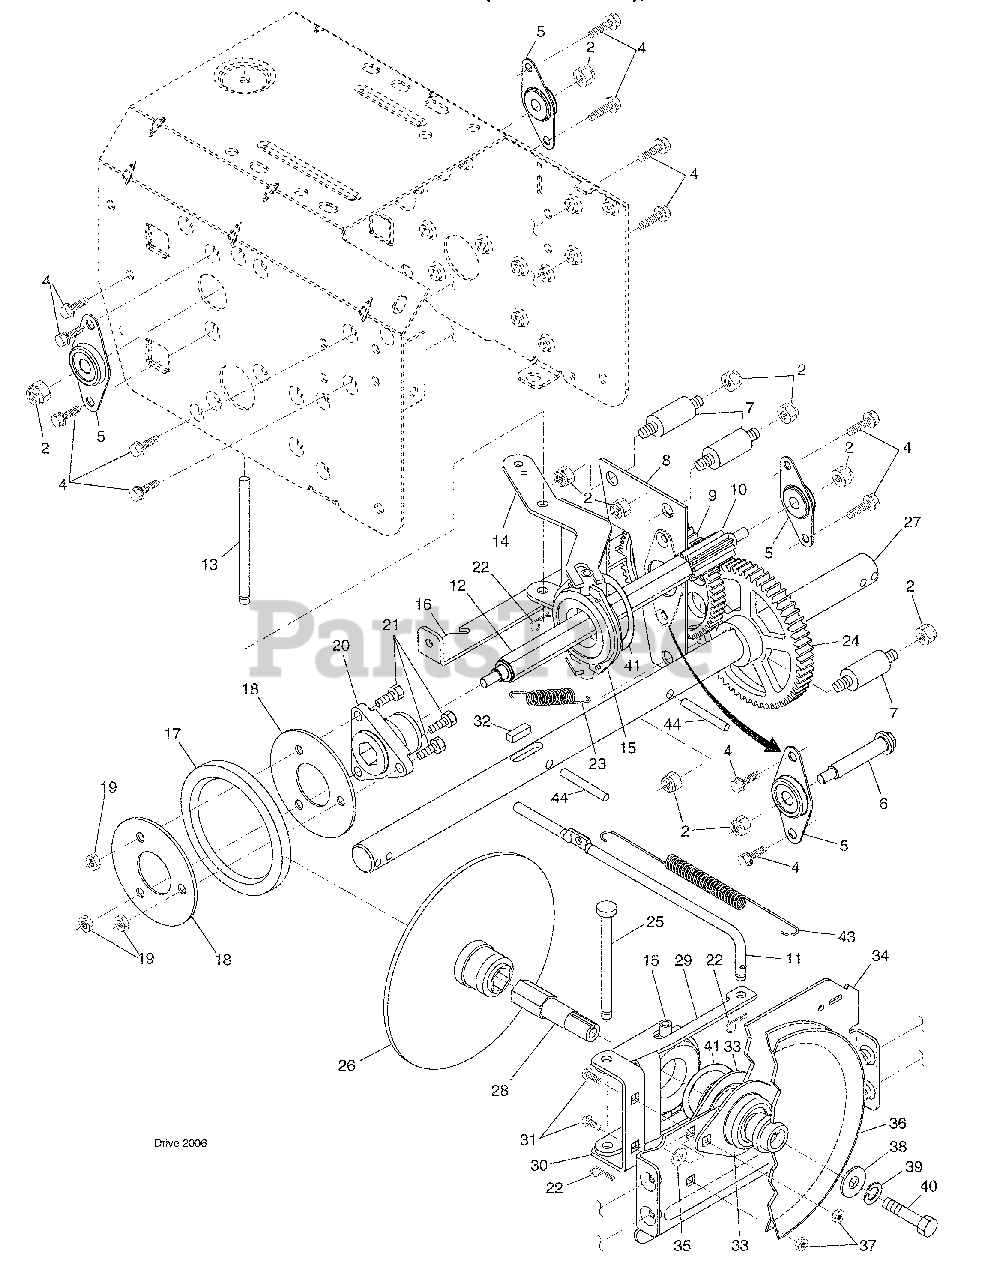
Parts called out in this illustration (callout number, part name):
2	Nut, Lock 5/16-18
4	Screw, Hex Head 5/16-18 x 1/2
5	Bearing, Flange
6	Shaft, Auxiliary
7	Spacer, Plate
8	Plate, Auxiliary
9	Gear, Intermediate (12/58)
10	Gear, Pinion
11	Rod, Clutch
12	Shaft, Long, Hex
13	Pin, Pivot
14	Lever, Shifter / Wheel
15	Trunnion Bearing Assembly
16	Bracket, Pivot, Shift
17	Ring, Rubber Wheel
18	Plate, Rubber Wheel
19	Nut, Lock 5/16-18
20	Hub, Rubber Wheel
21	Screw, Hex Head 5/16-18 x 7/8
22	Retainer, Hairpin
23	Spring, Bias
24	Gear, Axle (58 Teeth)
25	Pin, Pivot Lever
26	Plate Assembly, Drive
27	Shaft, Axle
28	Shaft, Short Hex
29	Lever, Shifter Plate
30	Bracket, Shifter Support
31	Bolt, Carriage 5/16-18 x 5/8
32	Key, Square 1/4 x 1/4 x 7/8
33	Bearing, Flange
34	Plate, Drive Mounting
35	Spacer, Bearing
36	Pulley, Traction Drive
37	Nut, Lock 5/16-18
38	Washer, Flat
39	Washer, Lock 5/16
40	Screw, Hex Head 5/16-18 x 3/4
41	Ring, Retaining
43	Spring, Return
